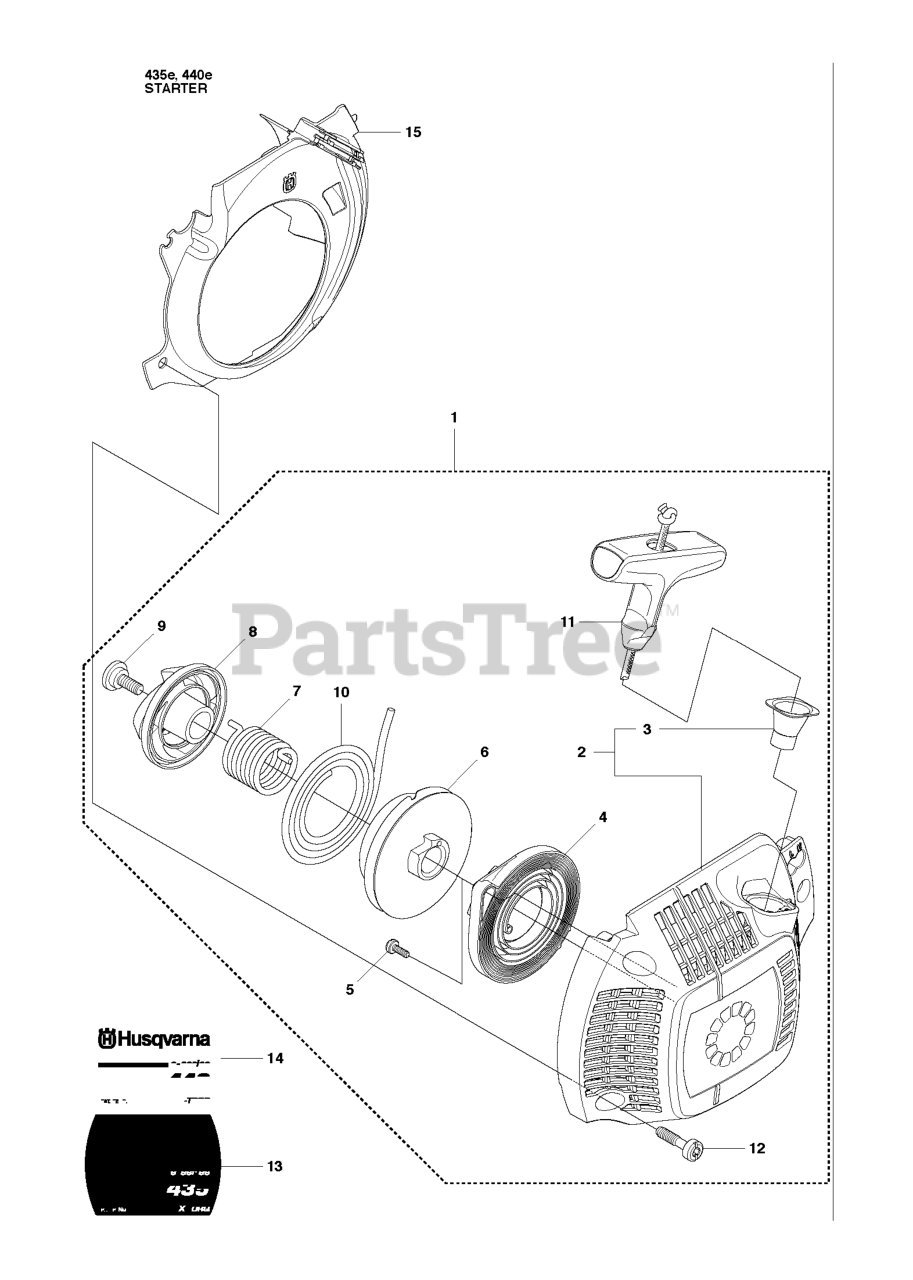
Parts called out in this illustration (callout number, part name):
1	STARTER ASSY
1	PLATE.ENGINE.PNT.23"FRAME.EDIP
2	STARTER HOUSING
2	CLUTCH.105.FT-LBS
3	EXHAUST.TUBE.LH.BS/TWIN
4	SPRING CASSETTE ASSY
4	EXHAUST.TUBE.RH.B&S.TWIN.INTEK
5	BRACKET MUFFLER MS431BLK
6	STARTER PULLEY
6	ARM IDLER
7	SPINDLE.IDLER
8	PULLEY.ENGINE
9	PULLEY, IDLER RAKE & ZTR
10	STARTER ROPE
10	T & B SPACER
11	STOP, CLUTCH, BLACK
12	GUARD.MUFFLER.WO.TOW.HITCHX431
13	LABEL 435 STARTER
13	MUFFLER ASM TWIN
14	LABEL 440 STARTER
14	SPRING, DECK DRIVE
15	%COOLING AIR CONDUCTOR
15	GASKET.MUFFLER
16	HEAT SHIELD
17	BEARING.FLANGED.PLASTIC.3/4ID
18	BOLT.FLANGE.1/2-13 X 2.75.GRD5
19	HCS 3/8-16X3-1/2 TAPBLT GR5 ZD
20	RHSNB 5/16C X 1
21	RP BOLT 5/16-18 X3/4 ZN/YEL GR
22	CLUTCH BOLT7/16-20X3.5 GR524HR
23	SCREW 3/8-16X1
24	SCREW.SOCKET.HEAD.5/16-18
25	SCREW.THDROL.5/16-18X3/4.TTY
26	NUT, 1/2-13 HEX FLG NYLOC ZD
27	5/16-18 NYLOC FLANGE NUT
28	NUT 3/8-16 NYLOC
30	WASHER 5/16 FLAT
